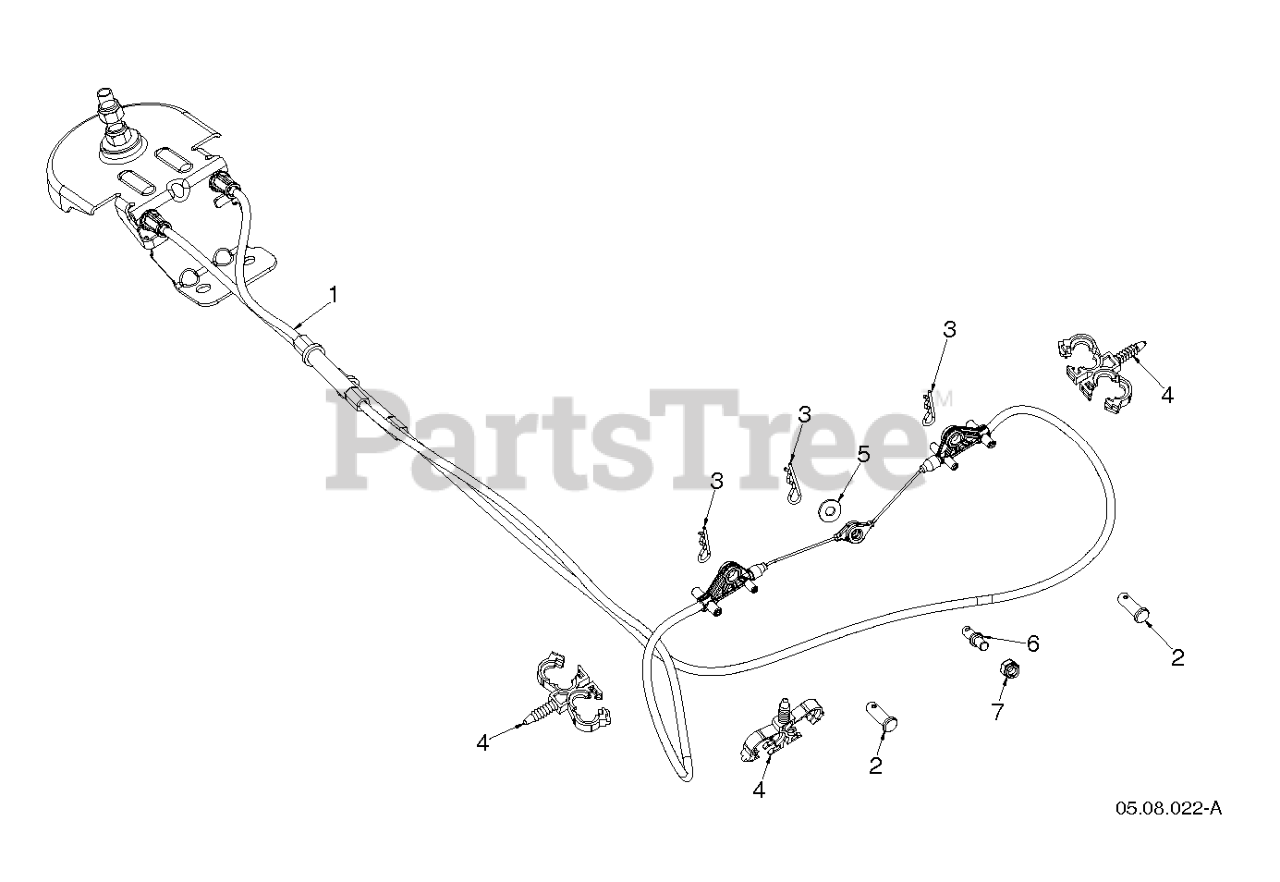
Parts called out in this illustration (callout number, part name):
2	PIN CLEVIS 5/16X.875
3	HAIRPIN.SOFT.ZINC.059X1.125
4	CLIP.CONDUIT.DOUBLE LOOP
5	WASHER FLAT_.250 X .625 X .06
6	Clevis Pins
7	NUT HEXAGON 1/4-20 ST ZPB
